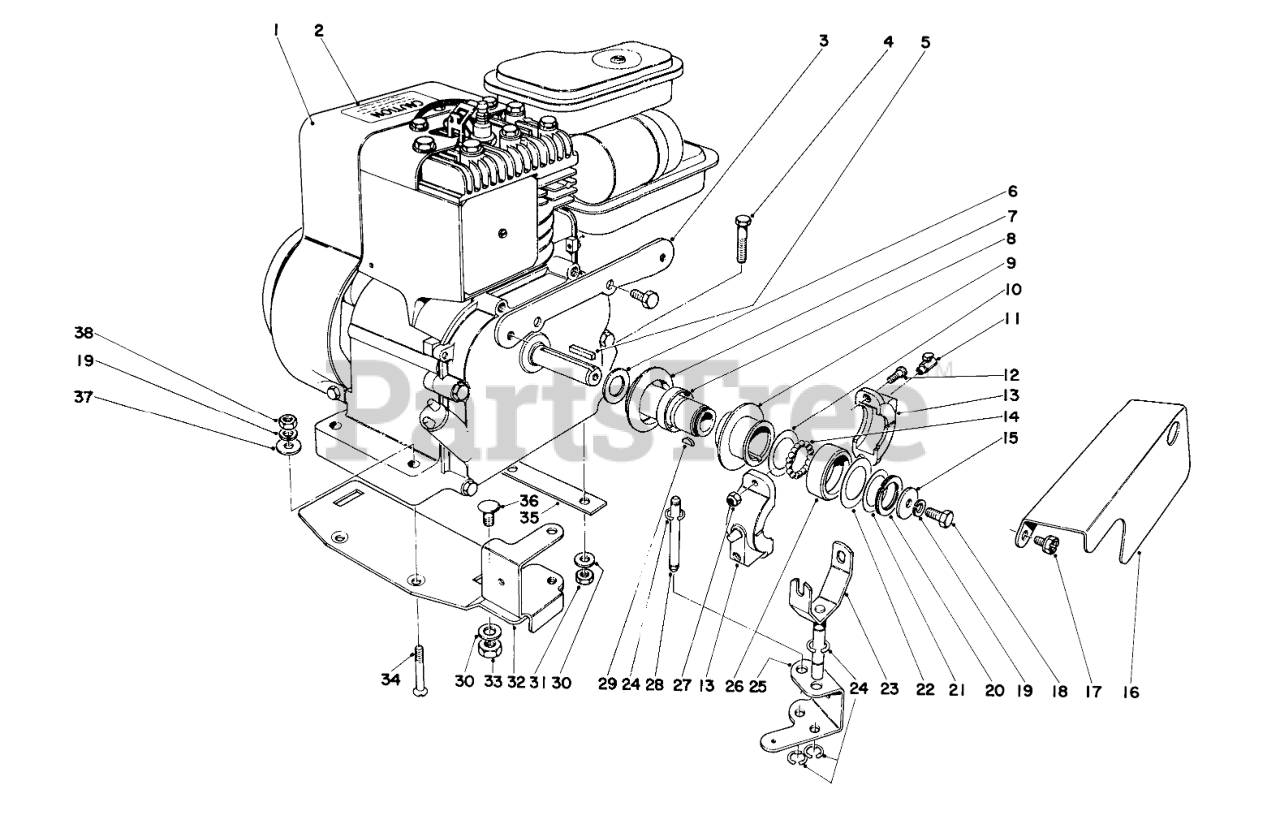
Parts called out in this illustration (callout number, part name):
1	Engine
2	Decal Caution
3	Bracket
4	Screw
5	KEY-SQUARE
6	Washer
7	CLUTCH BODY ASM
8	IDLER BUSHING
9	SLIDING FLANGE
10	Thrust Washer
11	OIL CUP (OBS)
12	SCREW
13	Slip Ring
14	BALL-STEEL
15	Washer
16	Belt Guard
17	Screw
18	SCREW-HH
19	WASHER-LOCK
20	Snap Ring
21	WASHER
22	WASHER
23	SHIFT FORK ASM R
24	RING-RETAINING, EXT
25	SHIFT FORK BRACKET
26	Shift Collar
27	NUT-LOCK
28	Pivot Shaft
29	KEY-WOODRUFF
30	WASHER-PLAIN
31	NUT-LOCK NI
32	Clutch Mounting Plate
33	Nut
34	Screw
36	BOLT-CARR
37	WASHER-FLAT
38	NUT-HEX
